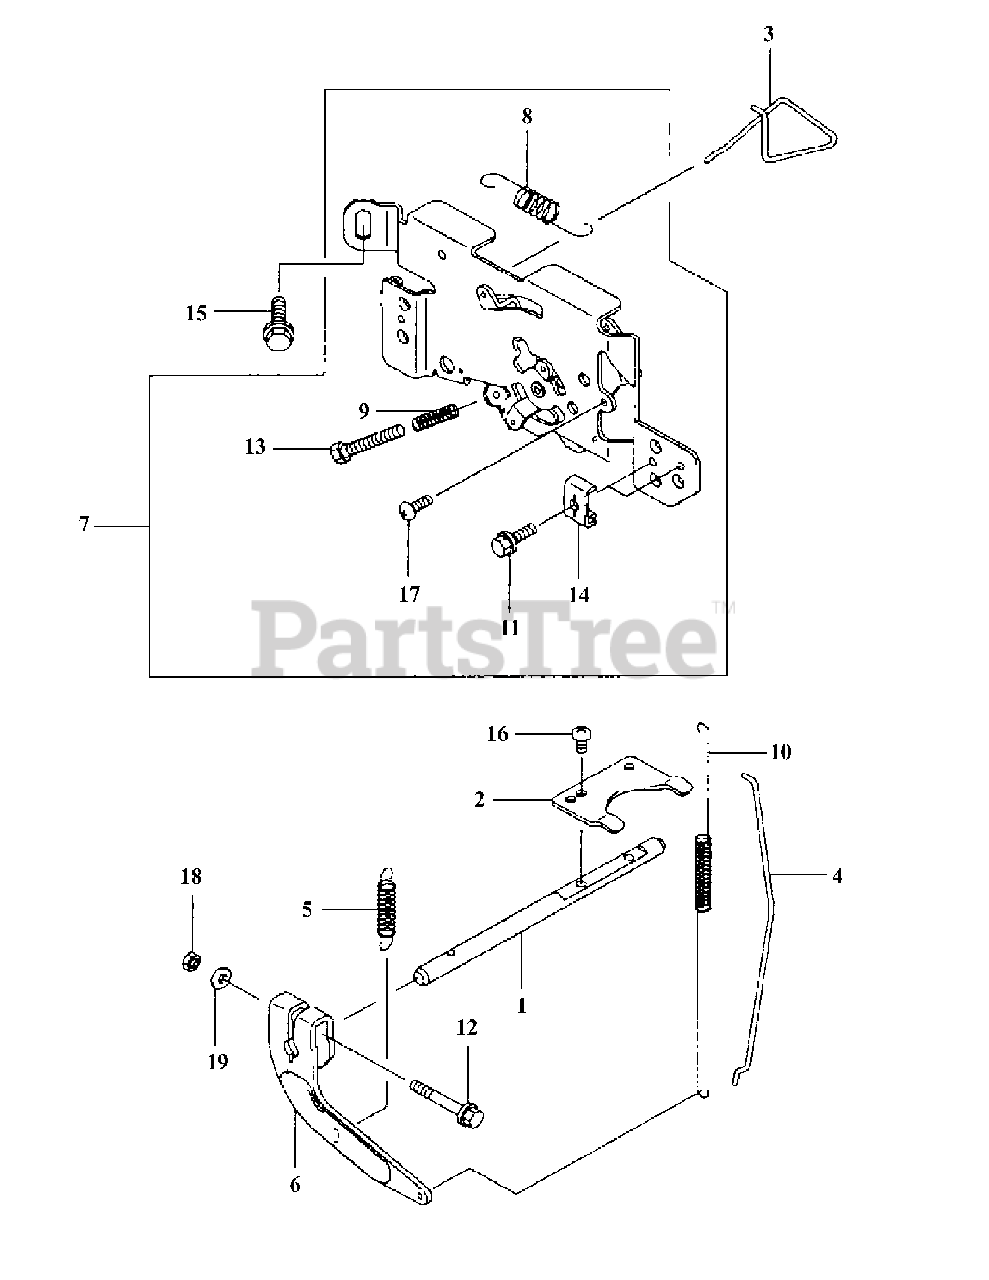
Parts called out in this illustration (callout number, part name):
1	Shaft
3	Link-Choke
4	Link
5	Spring-Governor
6	Arm-Governor
7	Panel-Comp-Control
8	Spring
19	Washer-Plain
